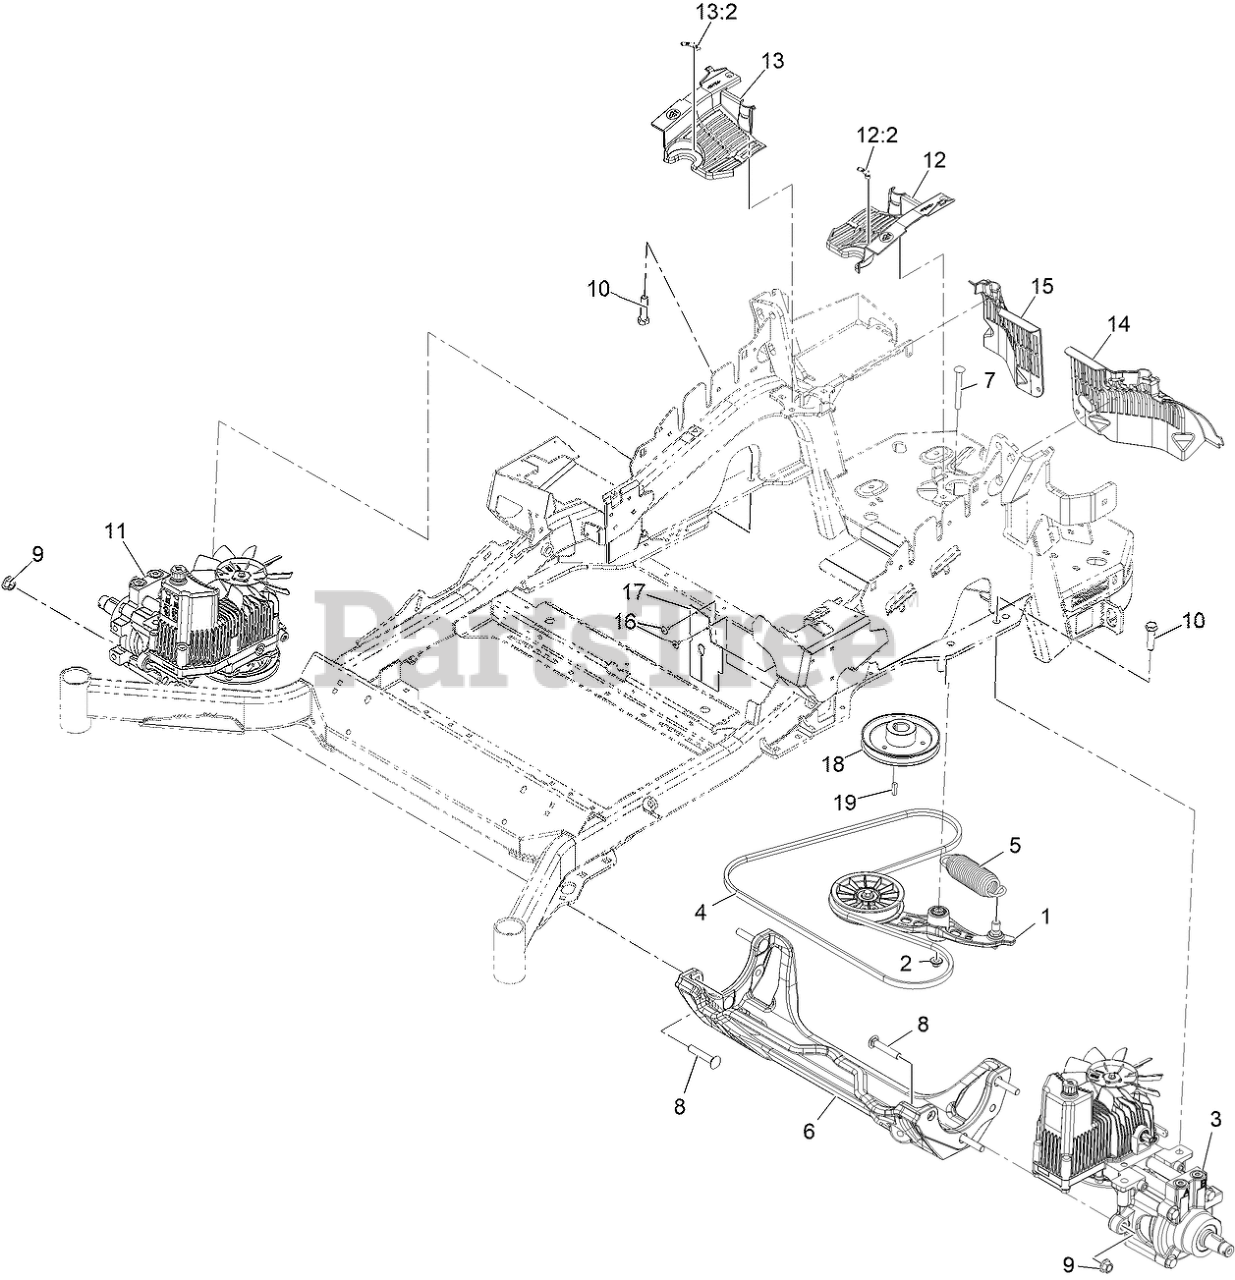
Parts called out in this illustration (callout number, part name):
1	PUMP IDLER ASM
2	Nut-Nyloc 3/8-16 Flg
3	HYDRO-LH
5	SPRING-EXTENSION
6	CRADLE-HYDRO
7	BOLT-SHOULDER, CARRIAGE 3/8-16 X 3 1/2
8	SCREW-CARR
9	Nut-Lock 1/2-13
10	SCREW-HH
11	HYDRO-RH
12	LH HYDRO GUARD ASM
12:2	DECAL-OIL, HYDRO
13	RH HYDRO GUARD ASM
13:2	DECAL-OIL, HYDRO
14	GUARD-HYDRO, REAR (LH)
15	GUARD-HYDRO, REAR (RH)
16	RIVET-POP
17	DEFLECTOR-AIR FLOW
18	SHEAVE, W/HUB
